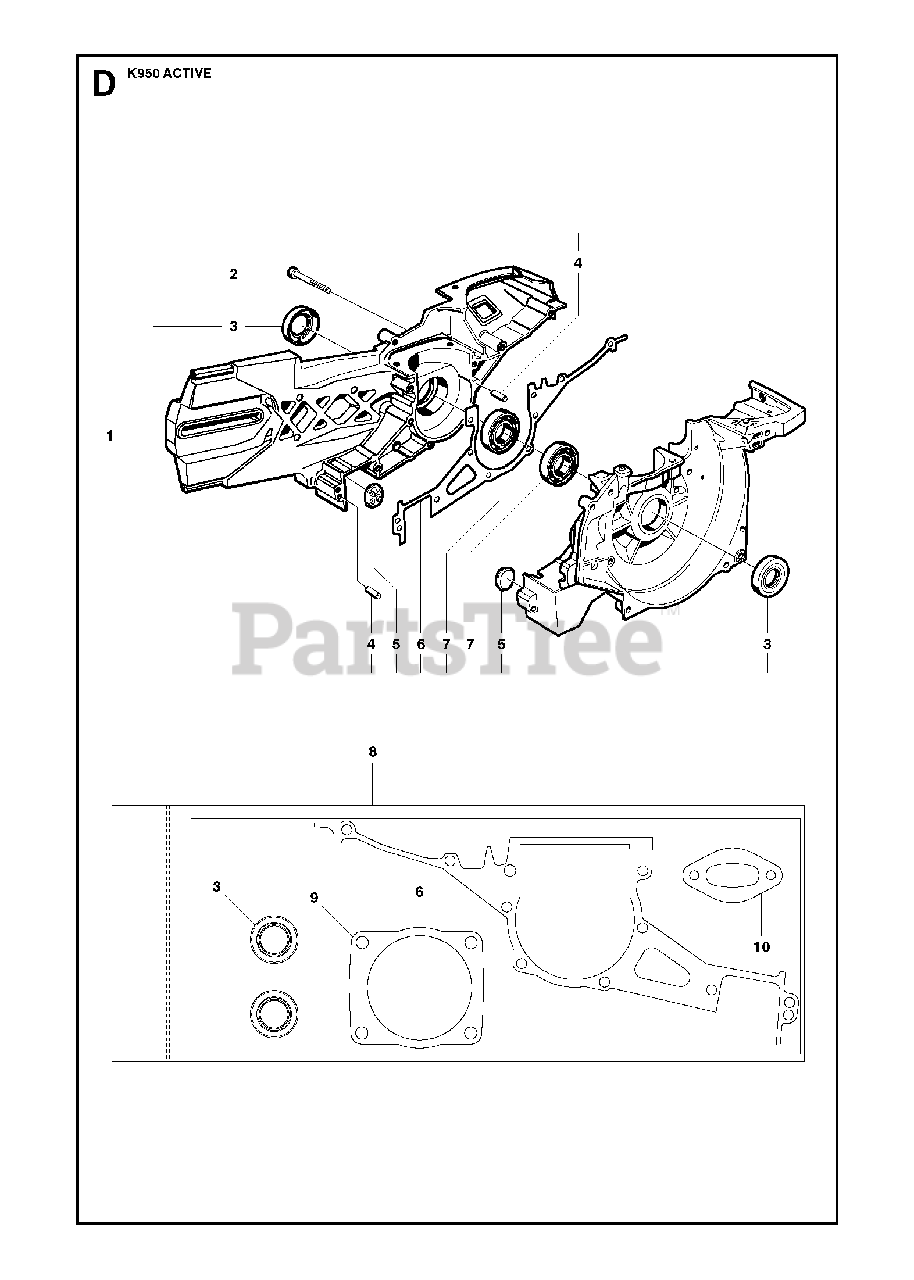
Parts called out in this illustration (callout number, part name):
1	CRANKCASE ASSYIncl. 2, 3, 4, 5, 6, 7
3	SEALING RINGGasket kit 8
4	PARALLEL PIN
7	BALL BEARING
9	CYLINDER BASE GASKET
10	GASKET
